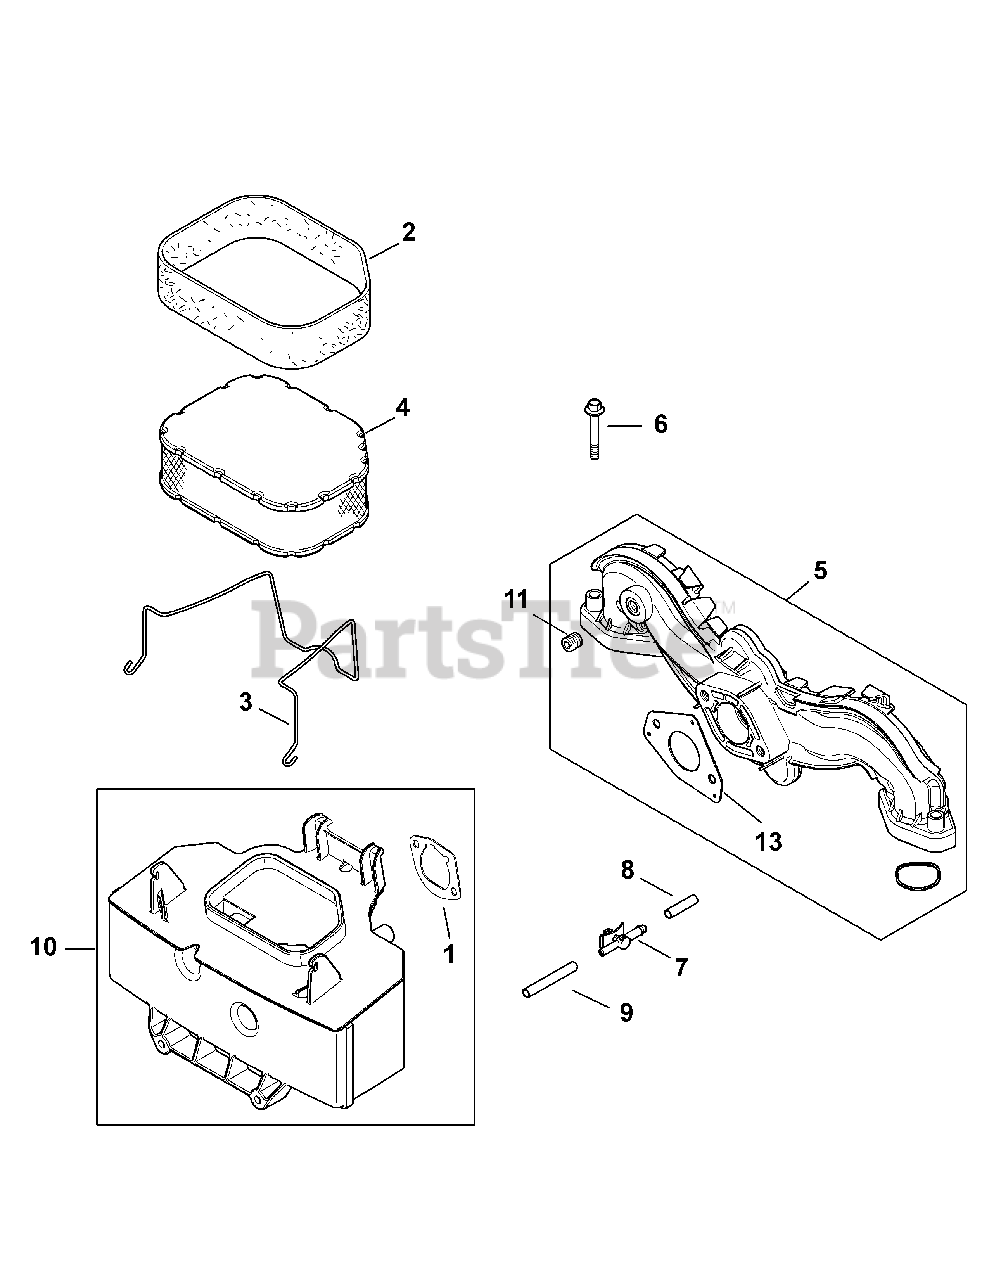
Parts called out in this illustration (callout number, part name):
1	Air Cleaner Base Gasket
2	Pre-Cleaner Element
3	Air Cleaner Element Latch
4	Air Filter Element
5	Intake Manifold Kit
6	Flange Screw, M6 x 1.0 x 40
7	Evaporative Connector
8	Evaporative Mask
9	Evaporative Hose, 20"
10	Air Cleaner Base
11	Pipe Plug, 1/8
12	Carburetor Gasket
13	Intake Port O-Ring
